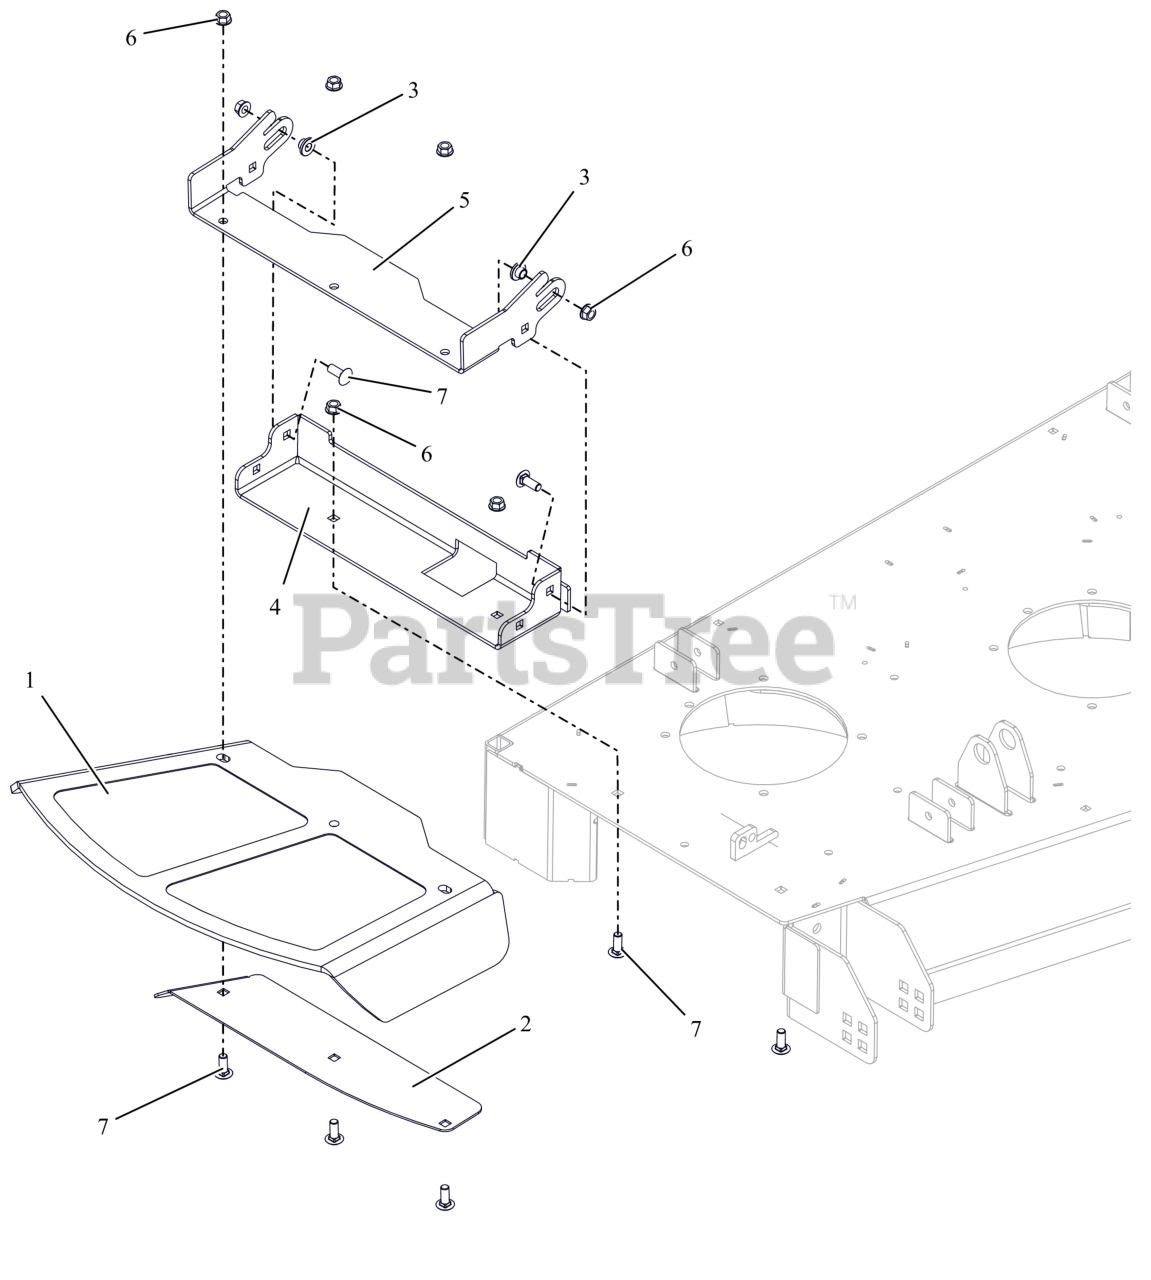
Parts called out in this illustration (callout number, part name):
1	CHUTE, FORMED RUBBER DISCHARGE
2	48-60 DISCH CHUTE CLMP PLT-RED
3	BSHG-FLG .385X.500X.875X.406
4	BASE, DISCH CHUTE MTG W/SAFETY
5	BRKT- CHUTE MTG
6	NUT-LK-CTR-FLG .375-16 GF ZCC
7	BLT,RHSSN .38-16X1.00 G5 ZCC
